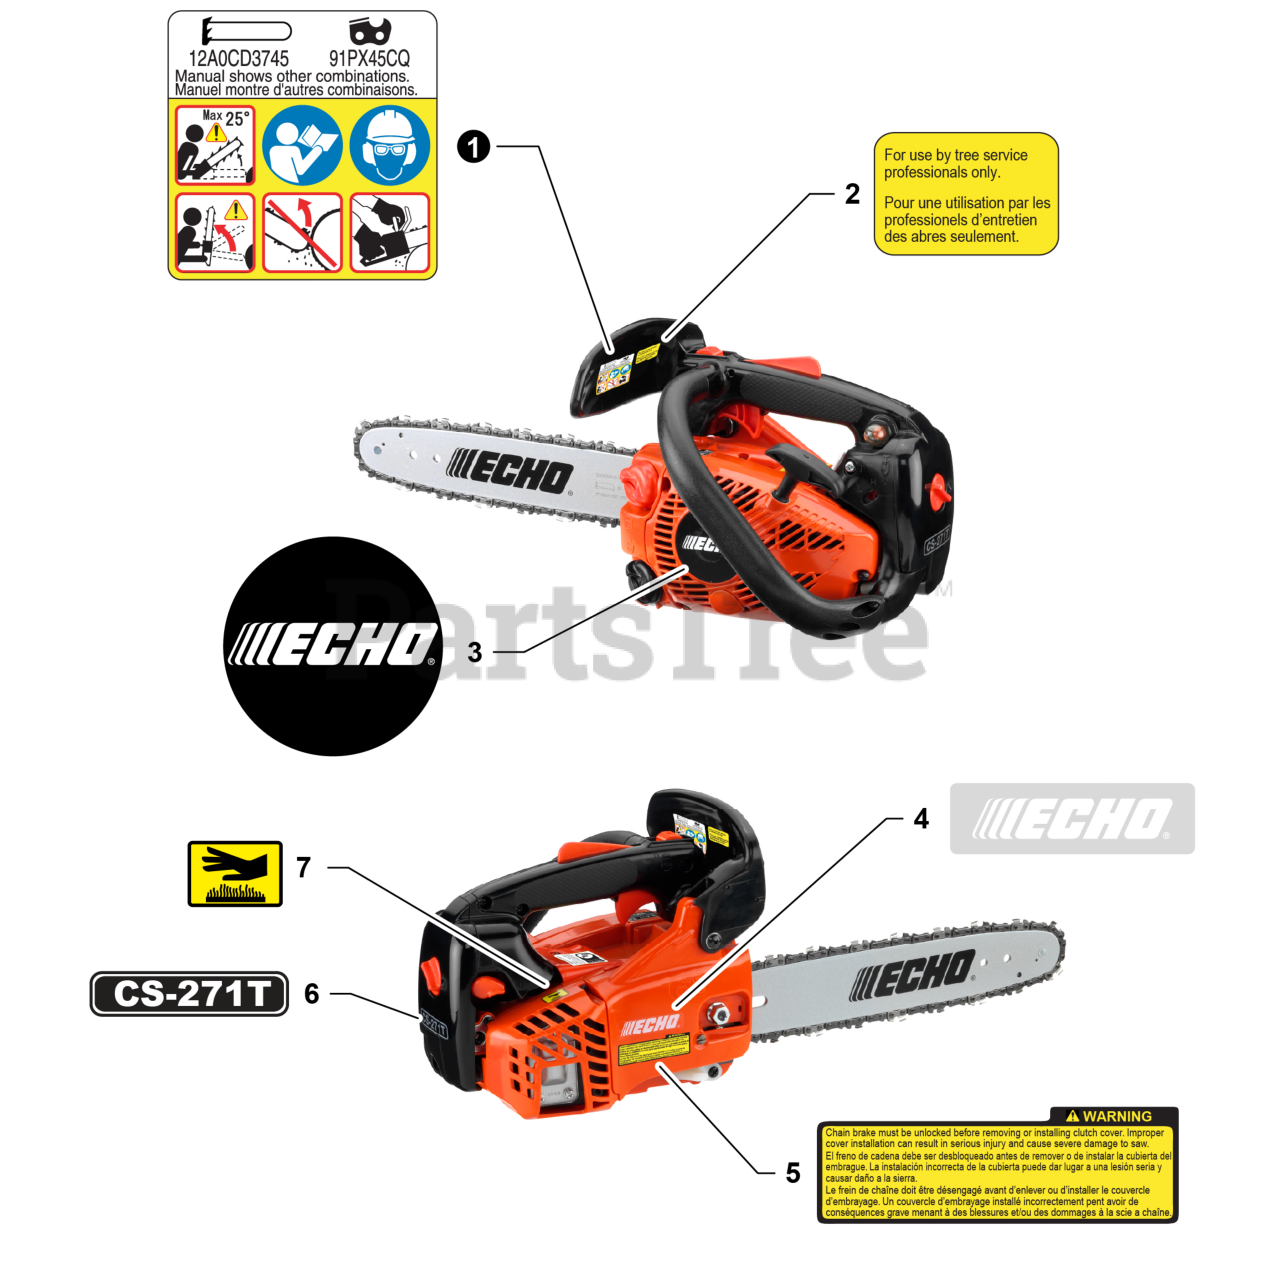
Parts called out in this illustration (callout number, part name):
1	LABEL - CAUTION
2	LABEL - CAUTION - PROFESSIONALS ONLY
3	LABEL - STARTER - ECHO
4	LABEL - ECHO
5	LABEL - WARNING
6	LABEL - MODEL CS-271T
7	LABEL - CAUTION - HOT
